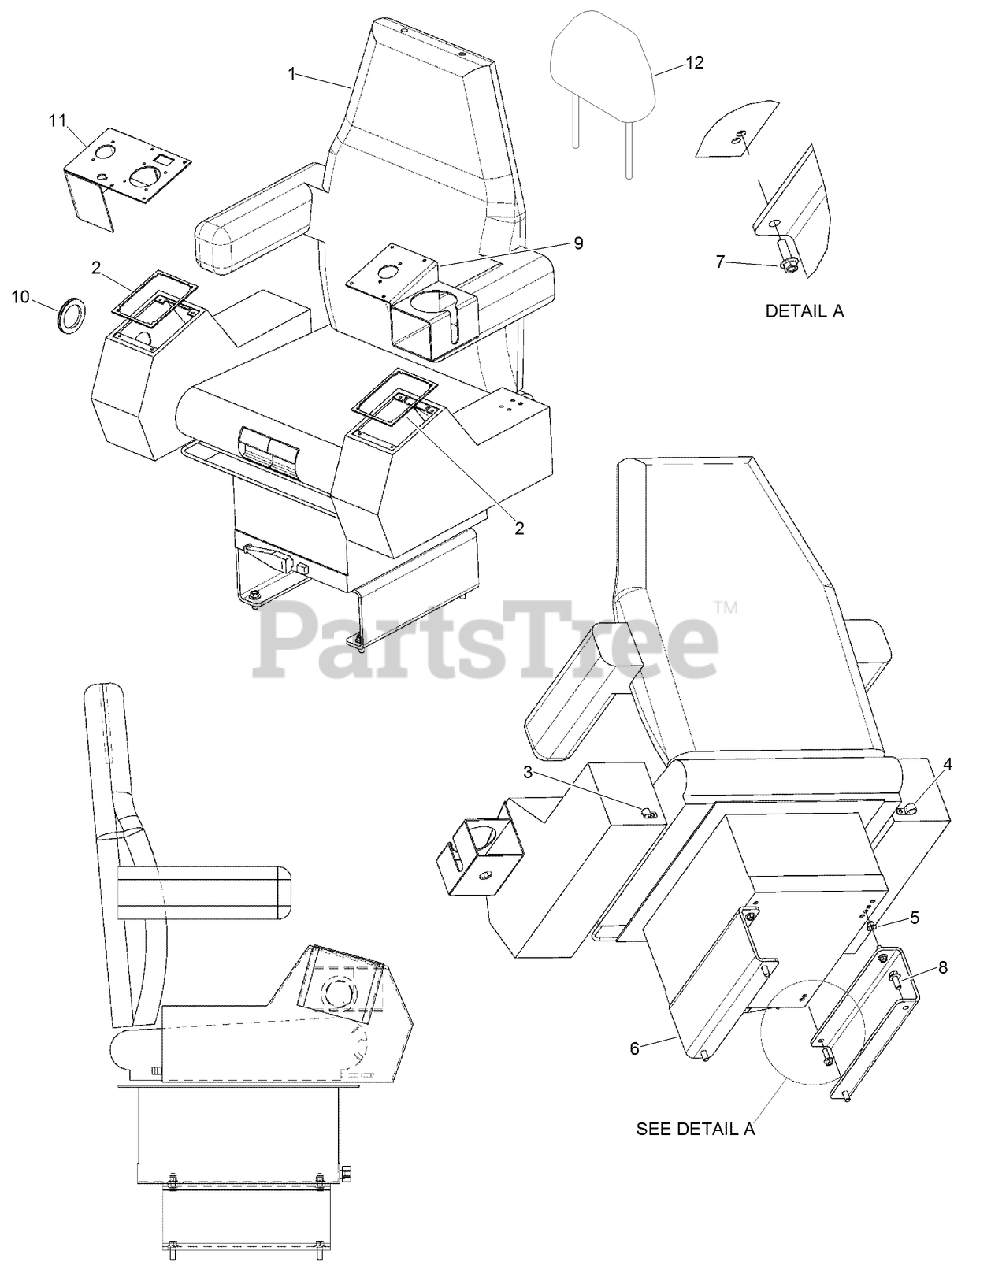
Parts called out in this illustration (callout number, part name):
1	ARMCHAIR-OPERATOR
2	SPACER - Plate
3	CLAMP - Insul 12.7mm M6 Bolt, ZND
4	CLAMP - Insul 17.5mm M6 Bolt, ZND
5	NUT-TORQUE, PREVAILING
6	RISER - Operator Seat
7	SCREW-HH
8	SCREW-FLANGE
9	CUP HOLDER - Weldment
10	TRIM - Edge
11	WELDMENT - Joystick Mount
12	OPTION - Head Rest
